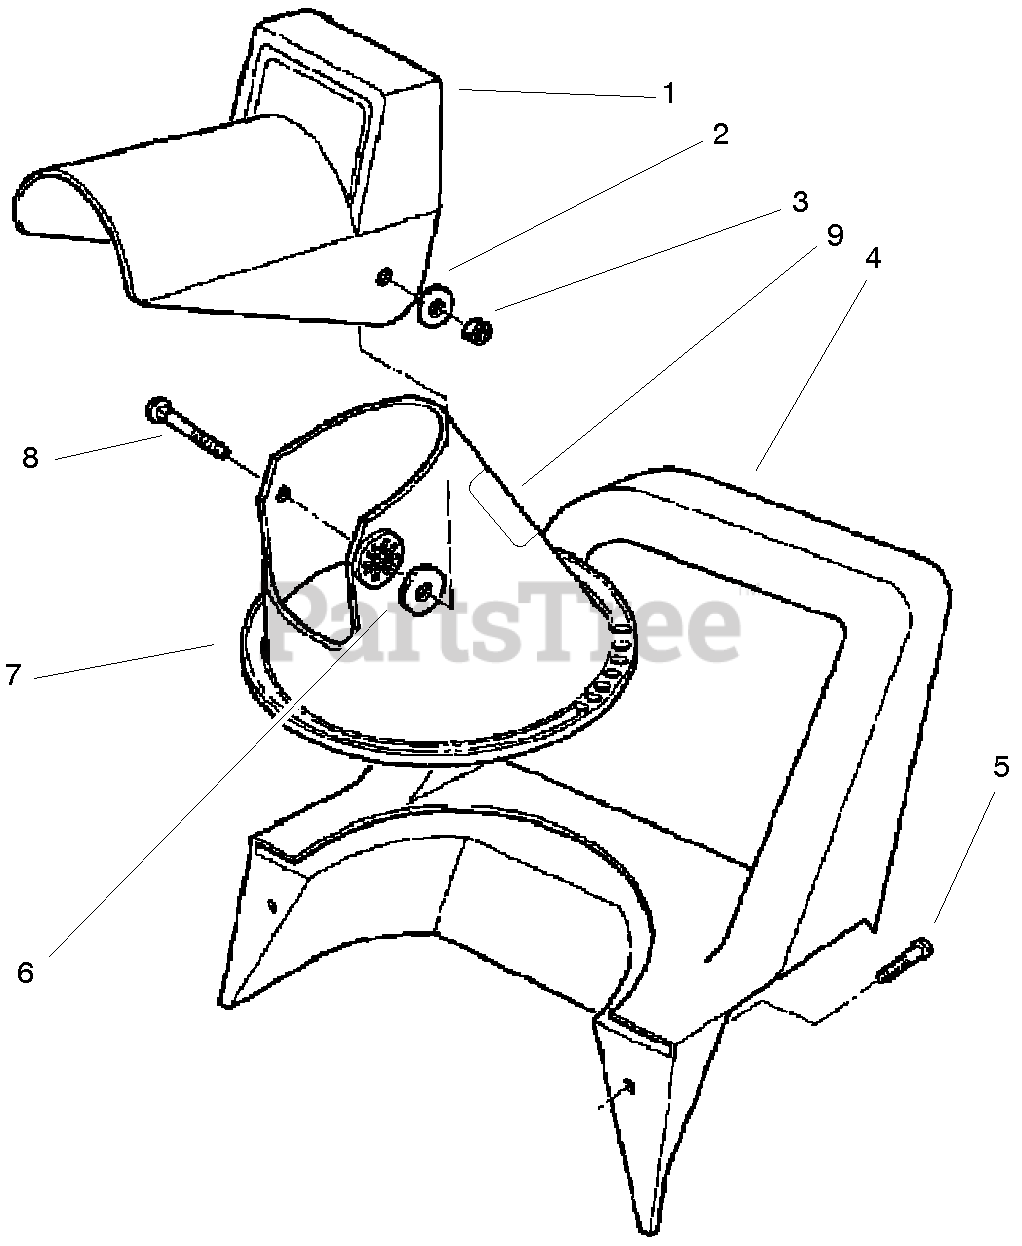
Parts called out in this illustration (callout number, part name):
1	Chute-Deflector
2	WASHER-FLAT
3	NUT-LOCK, NI
4	Handle-Middle
5	SCREW-PPH
6	WASHER-RUBBER
7	Chute-Lower
8	BOLT-CARR
9	Decal-Auger Danger
